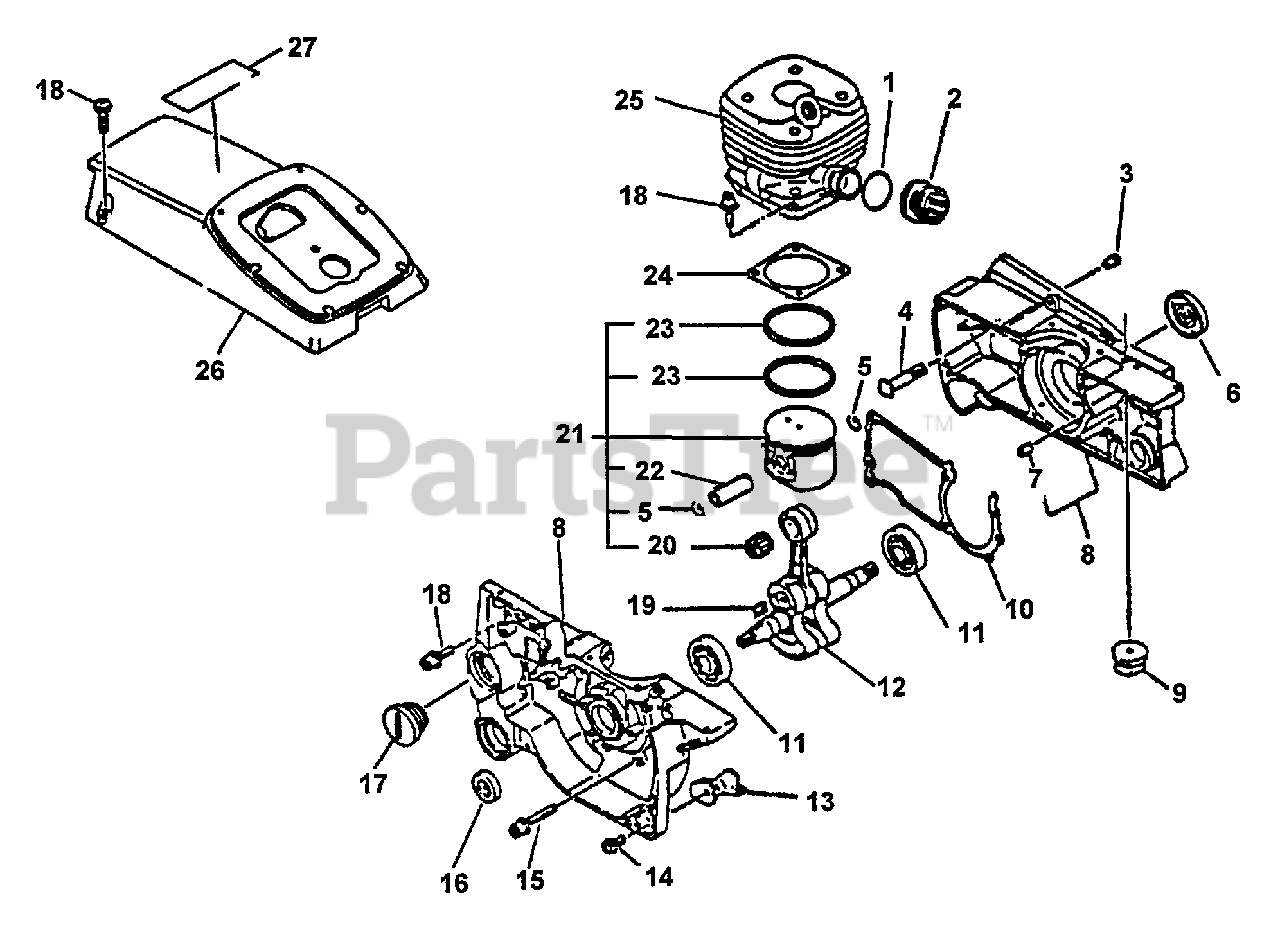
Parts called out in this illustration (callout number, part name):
2	BELLOWS, INTAKE
3	VENT, TANK
4	STUD, GUIDE BAR
5	RING, RETAINING
6	SEAL, OIL
7	PIN - LOCATING
8	CRANKCASE KIT
9	CUSHION - A
10	GASKET, CRANKCASE
11	BEARING, BALL - 6202
12	CRANKSHAFT ASSY
14	SCREW - 5X14
15	SCREW - 5X35
16	SEAL, OIL
17	PLUG
18	SCREW - 5X20
20	BEARING, NEEDLE
21	PISTON KIT
22	PIN, PISTON
23	RING, PISTON
24	GASKET, CYLINDER
25	CYLINDER KIT
26	COVER, ENGINE
27	LABEL - CAUTION
